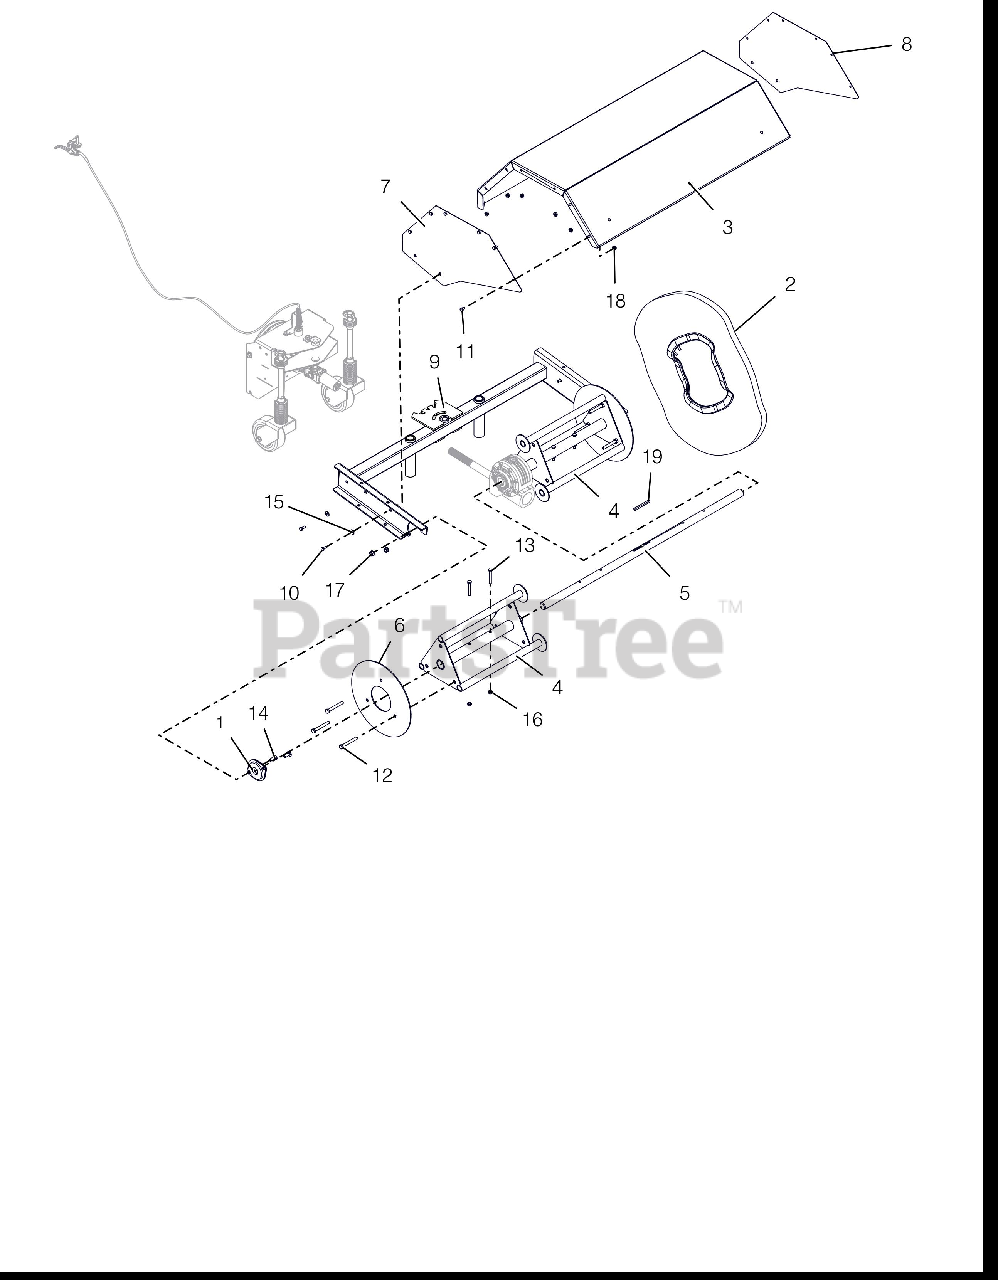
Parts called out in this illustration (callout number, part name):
1	BEARING,2 BOLT FLANGE 1-1/8 ID
2	KIT, BRISTLE - SET OF 18
3	COVER, TOP - 36" BRUSH W/DECAL
4	PB36 DRIVE CORE SERVICE KIT
5	CENTER, SHAFT
6	PLATE, END RETAINER
7	WLDT, SIDE COVER - RH
8	WLDT, SIDE COVER - LH
9	FRAME, POWER BROOM 36"
10	@BLT-HEX .25-20X.75 GR5 YWZC
11	@BLT-HEX .25-20X.50 GR5 YWZC
12	BLT-HEX .38-16X3.00 GR5 FTH YZ
13	@BLT-HEX .31-18X2.25 GR5 YWZC
14	@BLT-RDHDSQNK .38-16X1.00 G5YZ
15	@WSHR-FL-STL.312X.734X.065 YWZ
16	@NUT-LK-CTR .31-18 YWZC
17	@NUT-LK-TOP-FLG .38-16 YWZC
18	@NUT-LK-TOP-FLG .25-20 YWZC
19	KEY .25 X .25 X 3IN
